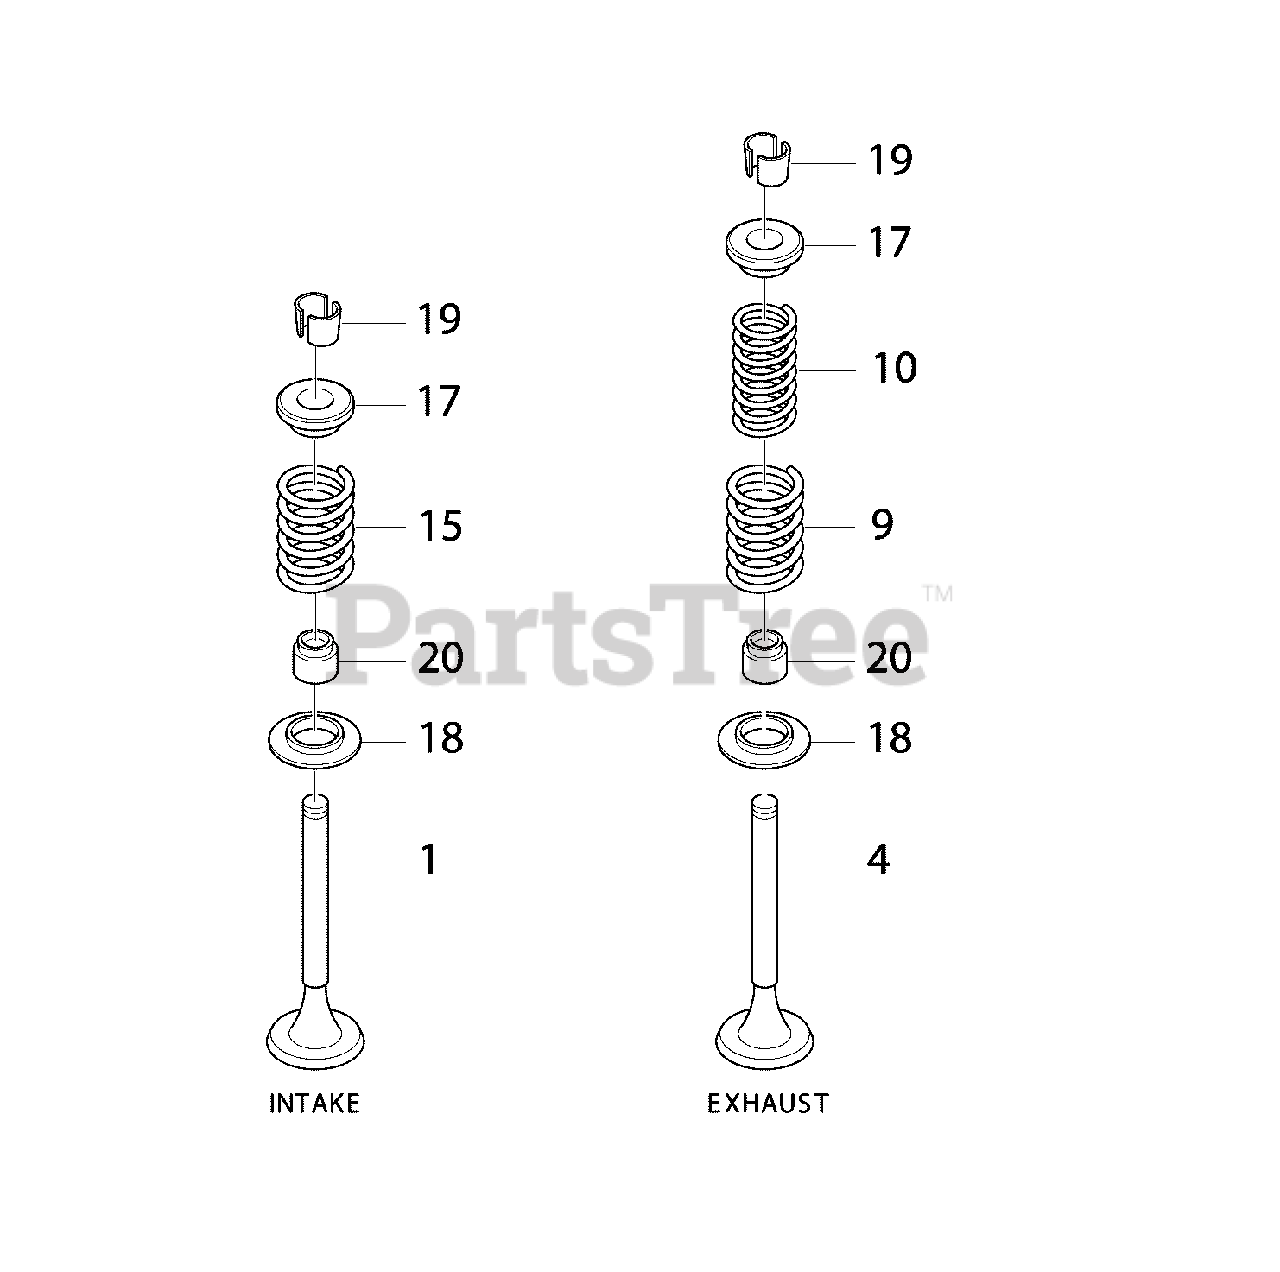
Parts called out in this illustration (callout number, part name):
1	* VALVE, INTAKE
4	* VALVE, EXHAUST
8	* SPRING, EXHAUST VALVE
9	* SPRING, VALVE
10	* SPRING, EXHAUST VALVE
15	* SPRING, VALVE
17	* RETAINER, VALVE SPRING
18	* WASHER
19	* KEEPER
20	* SEAL, VALVE STEM
